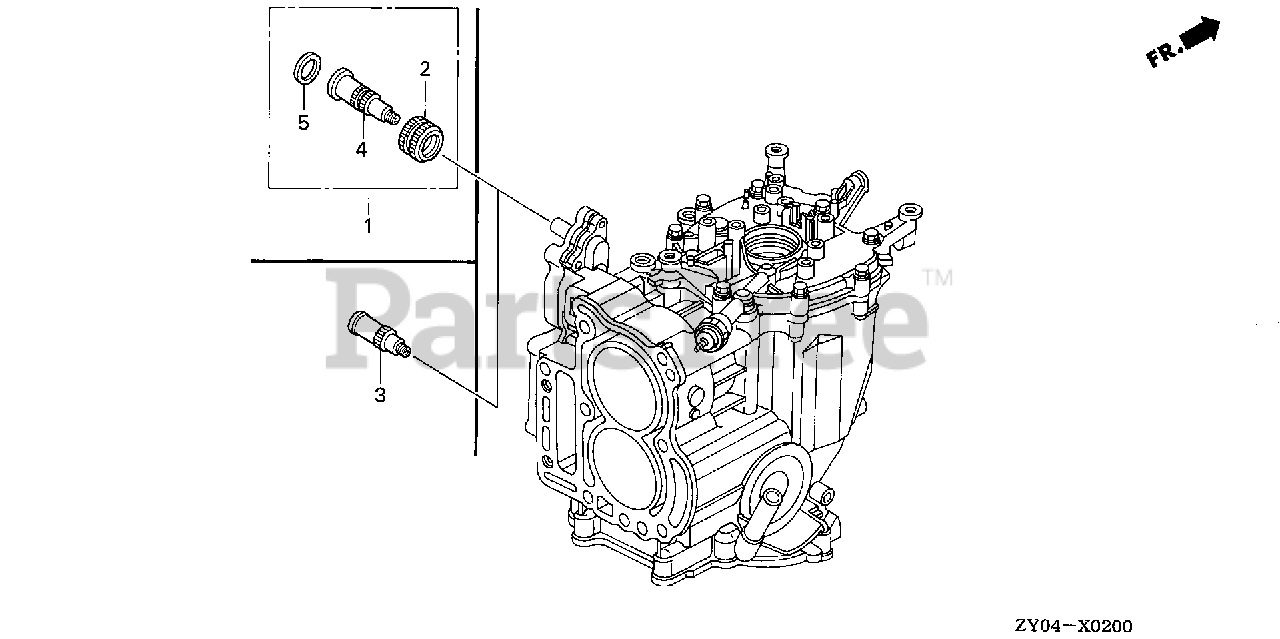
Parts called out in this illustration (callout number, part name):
1	JOINT KIT, WATER HOSE
2	NUT, WATER MOUTH
3	JOINT, WATER HOSE
4	JOINT, WATER HOSE
5	SEAT, WATER MOUTH
